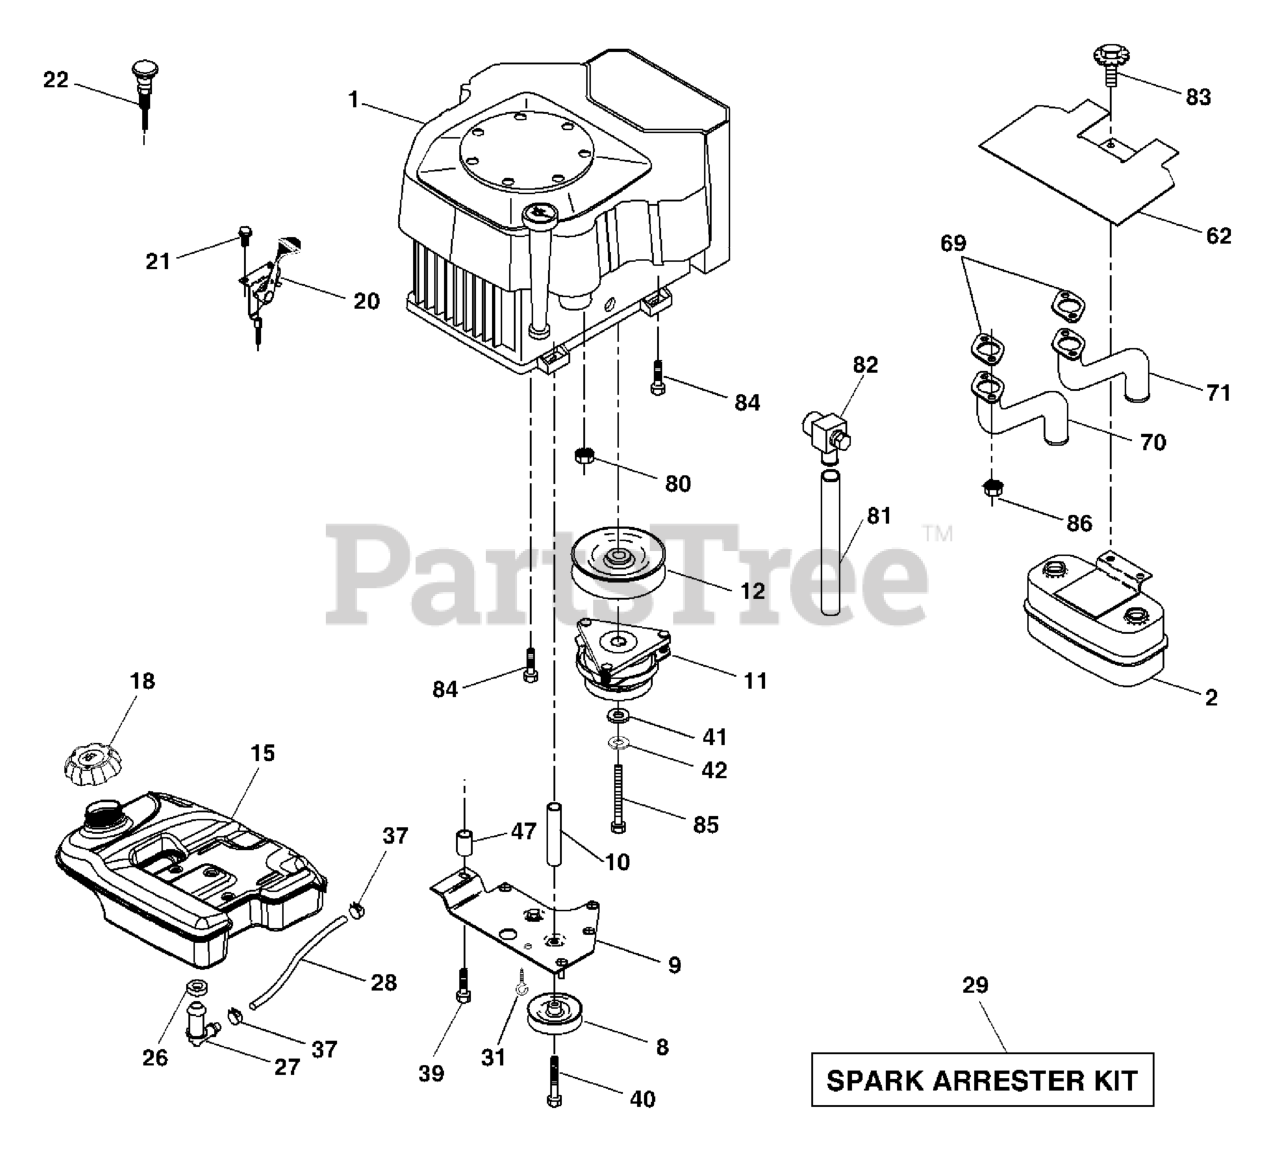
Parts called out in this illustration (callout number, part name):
2	MUFFLER.TWIN.CYL.LOW.TONE
8	RP.IDLER GROOVED
9	KEEPER ASM BELT ENGINE
11	CLUTCH MZ ZTR GT.48/54"1.125"
12	PULLEY ENG VGT ELECT CLUTCH
15	TANK.FUEL.5.0 LEFT.FILL.YTGT
18	TANK CAP
20	THROTTLE CONTROL
21	SCREW
22	CONTROL, CHOKE
26	BUSHING OUTLET T
27	STEM FUEL TANK
28	HOSE
29	KIT.SPARK ARRESTOR 794945 B&S
37	HOSE CLAMP
39	SCREW TT 3/8-16X2-1/4 UNC
40	Screw TT 3/8-16 x 4 unc
42	LOCKWASHER
62	RP SHIELD HEAT MUFFLER
69	Gasket
70	TUBE EXHAUST LH
71	TUBE.EXHAUST.LV675.COMMAND.RH
80	FLANGE NUT
81	TUBE, DRAIN, OIL
82	VALVE.OIL.DRAIN.GT
83	BOLT.5/16-18UNCX3/4 W/SEMS.BLK
84	SCREW 3/8-16 X 1-1/2
85	BOLT HEX 7/16-20 X 3.75 GR. 5
86	NUT.HEX.FLANGE.TOPLOCK
